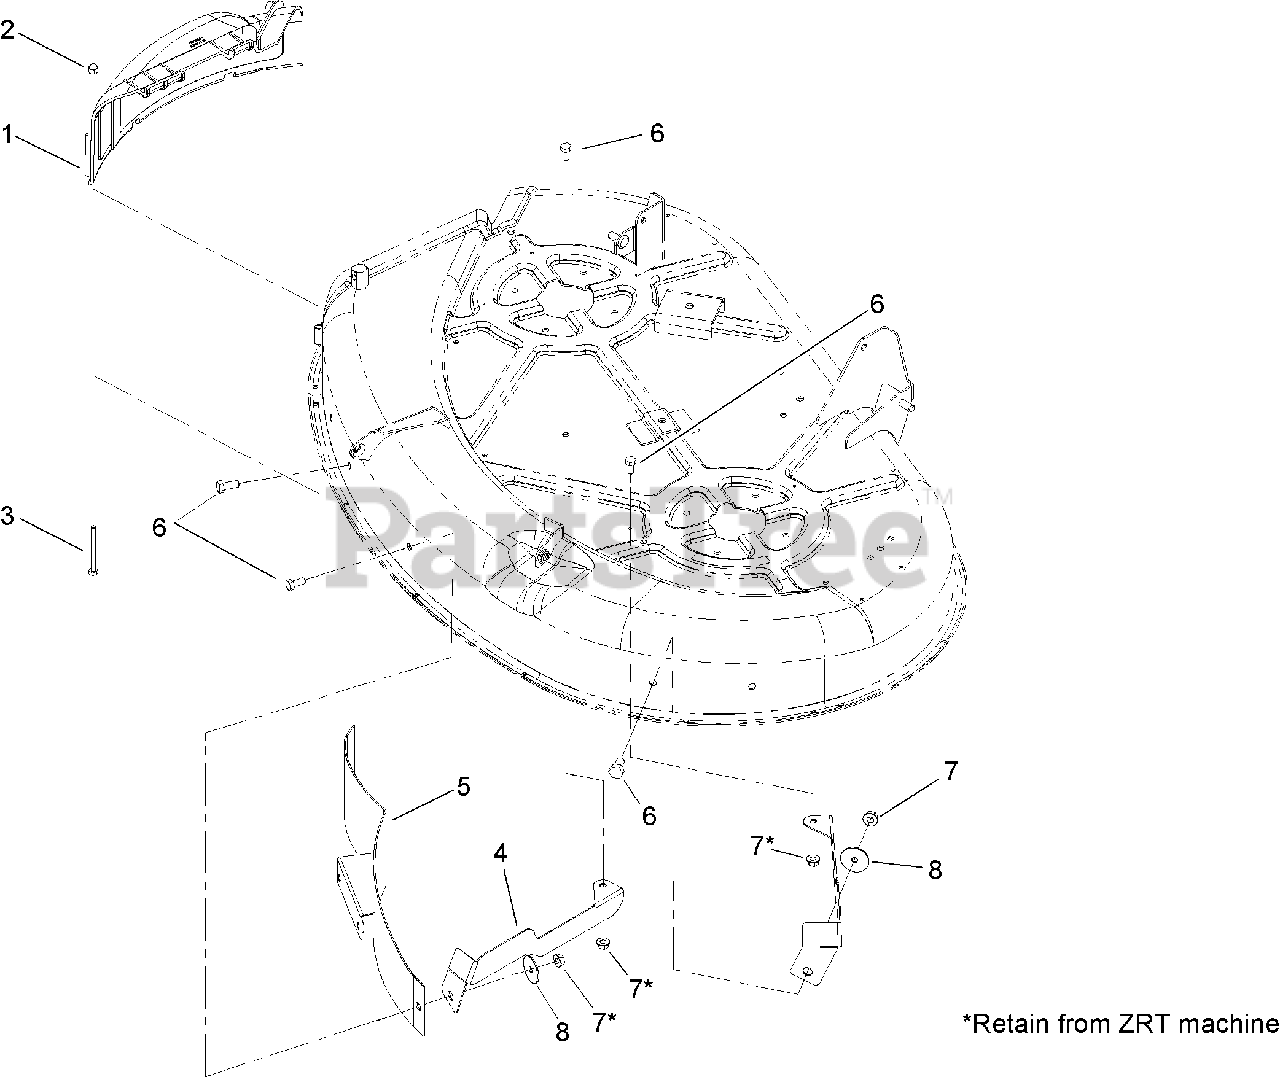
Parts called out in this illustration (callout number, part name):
1	COVER-DISCHARGE, DECK
3	SCREW-HH
4	BAFFLE-MULCH
5	BAFFLE-FRONT, RIGHT
6	SCREW-HH
8	WASHER-FLAT
